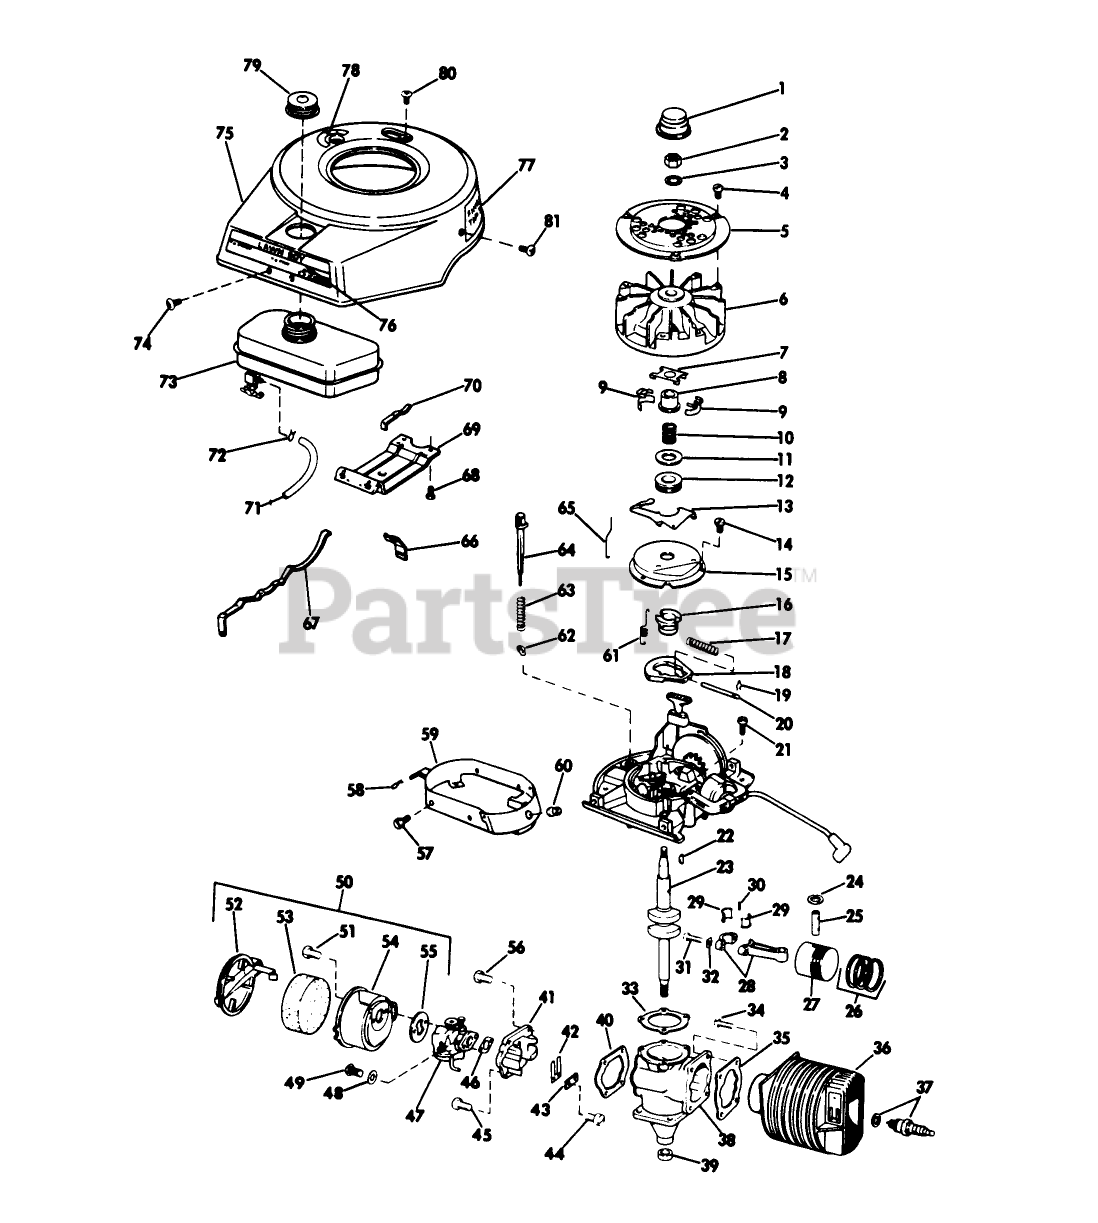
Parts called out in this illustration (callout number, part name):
8	COLLAR S
10	SPRING S
12	THRUST COLLAR S
13	LEVER-GOVERNOR S
14	SCREW S
15	DUST COVER S
16	SPARK ADV. S
17	SPARK ADV. SPRING S
18	FLYWEIGHT S
19	SPARK ADJ. SPRING
20	PIN,SPARK ADV. S
24	RING-RETAINING
29	LINER ASM
33	GASKET S
35	GASKET S
43	PLATE-BACKUP, REED
45	SCREW S
46	GASKET S
51	SCREW S
53	AIR FIL.ELEM S
56	SCREW S
57	SCREW S
60	NUT-CLIP
63	SPRING S
68	SCREW S
71	GAS LINE
72	CLAMP - HOSE S
76	Decal-Instructions
81	SCREW S
